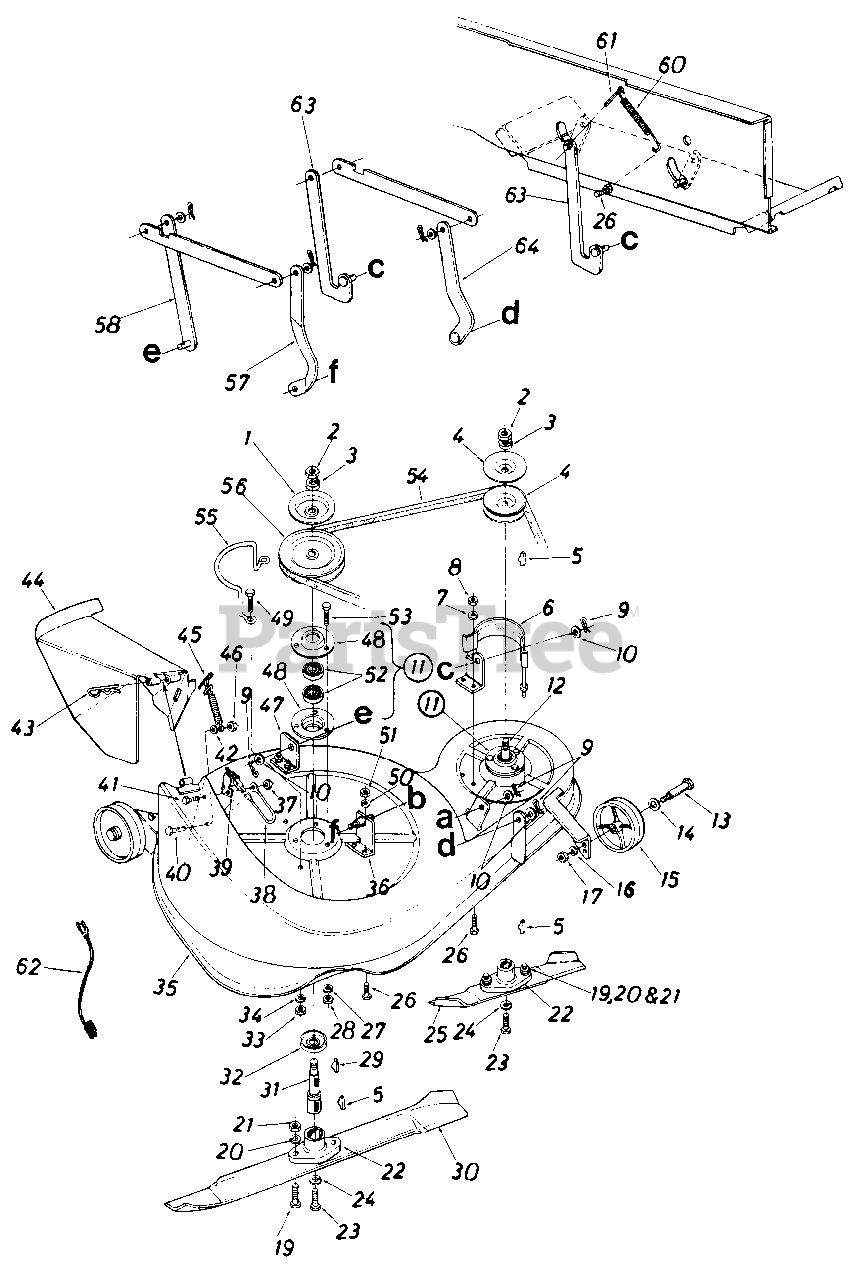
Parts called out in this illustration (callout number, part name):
1	Brake Disc
2	Hex Jam Nut 5/16-18 Thd.*
3	Bell-Wash. .630" I.D. x 1.25" O.D.
4	Pulley Ass'y. 3.5" O.D. x 5/8
5	#6 Hi-Pro Key 5132" x 5/8" Dia.
6	Belt Guard Ass'y. L.H.
7	L-Wash. 5/16" I.D.*
8	Hex Nut 5/16-18 Thd.*
9	Internal Cotter Pin 1/2" Dia.
10	Fl-Wash 531" I.D. x .93" O.D.
11	Blade Spind le Ass'y.
12	Blade Spindle
13	Shld. Bolt .498" Dia. x 1.635
14	Bell-Wash. .400" I.D. x .88" O.D.
15	Deck Wheel 5.0" x 1.38"
16	L-Wash. 5/16" I.D.*
17	Hex Nut 3/8-16 Thd.*
19	Hex Bolt 5/16-24 x 1.00" Lg. (Grade 5)
20	L-Wash. 5/16" I.D.*
21	Hex Nut 5/16-24 Thd.*
22	Blade Adapter
23	Hex Bolt 3/8-24 x 1.50" Lg. (Grade 5)
24	L-Wash. 3/8" I.D. H.D.
26	Hex Bolt 5/16-18 x .75" Lg.*
27	L-Wash. 5/16" I.D.*
28	Hex Nut 5/16-18 Thd.*
29	#6 Hi-Pro Key 5132" x 5/8" Dia.
31	Blade Spindle
32	Bearing Shield
33	Hex Nut 5/16-18 Thd.*
34	L-Wash. 5/16" I.D.*
35	36" Deck Ass'y.
36	Deck Hanger Brkt. R.H. Front
37	Hex Nut 1/4-20 Thd.*
39	Safety Switch
40	Truss Mach. Scr. 1/4-20 x .50" Lg.*
41	Hex Bolt 1/4-20 x .62" Lg.*
42	Fl-Wash. .281" I.D. x .50" O.D.
43	Internal Cotter Pin
44	Chute Deflector Ass'y.
45	Spring Latch Ass'y.
46	Hex Nut 1/4-20 Thd.*
47	Deck Hanger Brkt. R.H. Rear
48	Brg. Housing 1.85" I.D.
49	Hex Bolt 5/16-18 x .75" Lg.*
50	L-Wash. 5/16" I.D.*
51	Hex Nut 5/16-18 Thd.*
52	Ball Brg. .787" I.D. x 1.85" O.D.
53	Hex Bolt 5/16-18 x .75" Lg.*
54	"V"-Belt 1/2" x 71" Lg.
56	Pulley 6.0" O.D. x 5/8"
57	Link Deck Hanger Front R.H.
58	Link Deck Hanger Ass'y. Rear R.H.
61	Cotter Pin 1/8" Dia. x 1.25"
62	Wire Lead
63	Link Deck Hanger Ass'y. Rear L.H.
64	Link Deck Hanger Ass'y. Front L.H.
